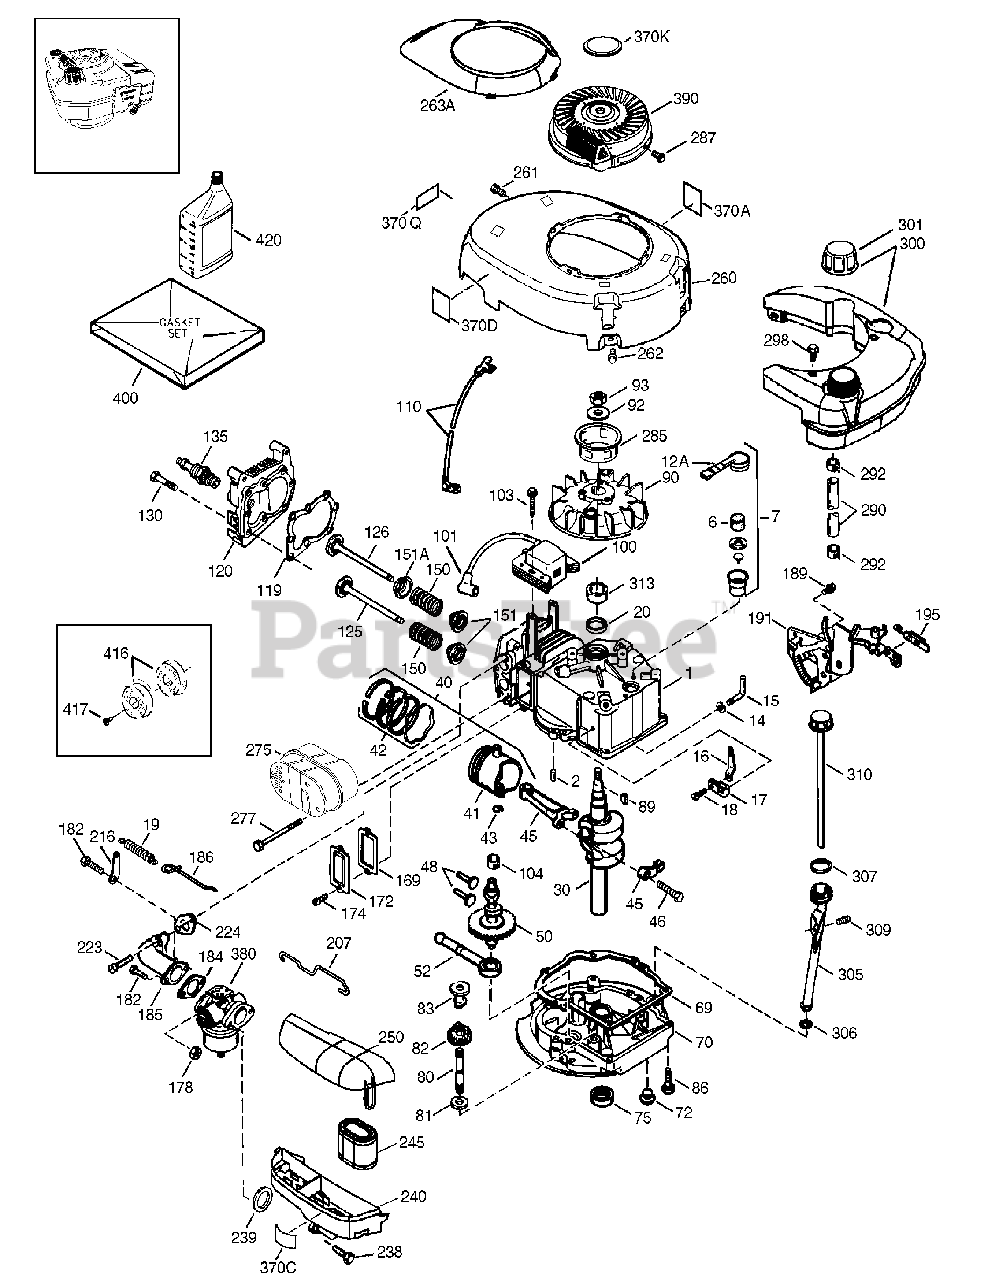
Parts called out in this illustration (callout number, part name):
1	Cylinder (Incl. 2, 20 & 150)
2	Dowel Pin
6	Breather Element
7	Breather Body ASM(Incl. 6 & 12A)
12A	Breather Cover & Tube
14	Washer
15	Governor Rod (Incl. 14)
16	Governor Lever
17	Governor Lever Clamp
18	Screw, Torx T-15
19	Extension Spring
20	Oil Seal
30	Crankshaft
40	Piston, Pin & Ring Set(Std.)
40	Piston, Pin & Ring Set(.010" OS)
41	Piston & Pin ASM(Std.)(Incl. 43)
41	Piston & Pin ASM(.010" OS)(Incl. 43)
42	Ring Set (Std.)
42	Ring Set (.010" OS)
43	Piston Pin RetainingRing
45	Connecting Rod ASM(Incl. 46)
46	Connecting Rod Bolt
48	Valve Lifter
50	Camshaft Exhaust
52	Oil Pump ASM
69	Mounting FlangeGasket
70	Mounting Flange(Incl. 72 thru 83, 306)
72	Oil Drain Plug
75	Oil Seal
80	Governor Shaft
81	Washer
82	Governor Gear ASM(Incl. 81)
83	Governor Spool
86	Screw
89	Flywheel Key
90	Flywheel
92	Belleville Washer
93	Flywheel Nut
100	Solid State Ignition
101	Spark Plug Cover
103	Screw, Torx T-15
104	Cam Bushing
110	Ground Wire
119	Cylinder Head Gasket
120	Cylinder Head
125	Exhaust Valve (Std.)(Incl. 151)
126	Intake Valve (Std.)(Incl. 151)
130	Screw
135	Resistor Spark Plug(RJ19LM)
150	Valve Spring
151	Valve Spring Cap
151A	Intake Valve Seal
169	Valve Cover Gasket
172	Valve Cover
174	Screw
178	Nut & Lock Washer
182	Nut & Lock Washer
184	Carburetor To IntakePipe Gasket
185	Intake Pipe
186	Governor Link
189	Screw
191	S.E. Brake Bracket(Incl. 195)
195	Terminal
207	Throttle Link
216	R.P.M. Adjusting Lever
223	Screw
224	Intake Pipe Gasket
238	Screw
239	Air Cleaner Gasket
240	Air Cleaner Body
245	Air Cleaner Filter
250	Air Cleaner Cover
260	Blower Housing
261	Screw
262	Screw
263A	Starter Grill
275	Muffler
277	Screw
285	Starter Cup
287	Screw
290	Fuel Line
292	Fuel Line Clamp
298	Screw
300	Fuel Tank(Incl. 292 & 301)
301	Fuel Cap
305	Oil Fill Tube
306	"O"-Ring
307	"O"-Ring
309	Screw
310	Dipstick
313	Spacer
370A	Lubrication Decal
370C	Primer Decal (3X)
370D	Caution Decal
370K	Starter Decal
370Q	Emissions Decal
380	Carburetor(Incl. 184)
390	Rewind Starter
400	Gasket Set
416	Spark Arrestor Kit
